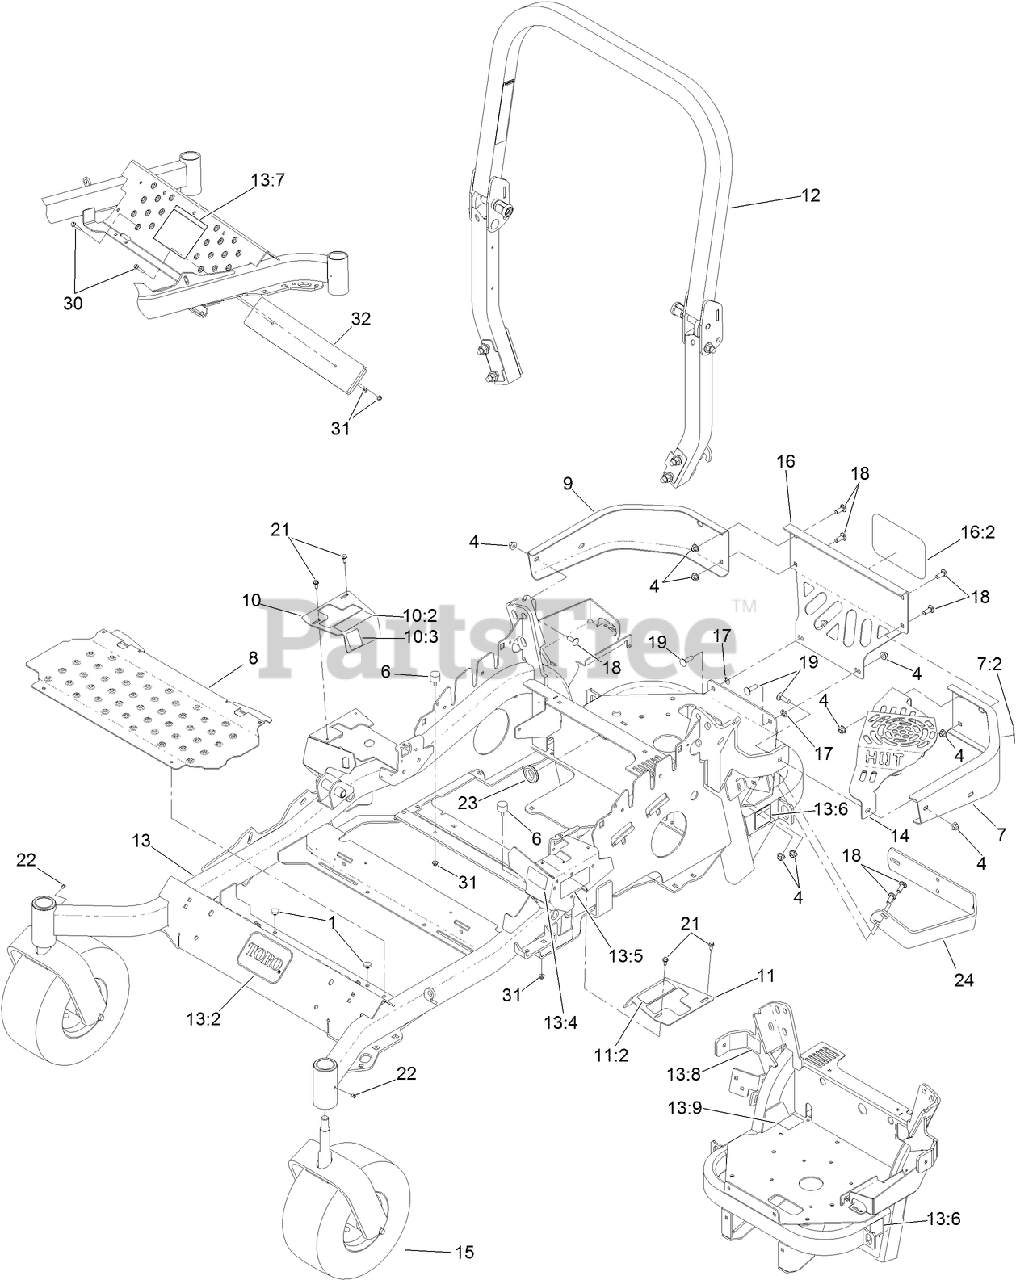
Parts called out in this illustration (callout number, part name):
1	BUMPER
4	NUT-HF, NI
6	BUMPER-RUBBER (W/ STUD)
7	BUMPER-REAR, LH
7:2	DECAL-CAUTION
8	FLOORPAN
9	BUMPER-REAR, RH
10	COVER ASM-MOTION CONTROL
10:2	DECAL-MOTION CONTROL
10:3	DECAL-PARK BRAKE
11	COVER ASM-MOTION CONTROL
11:2	DECAL-MOTION CONTROL
12	ROPS ASM
13	FRAME ASM
13:2	DECAL
13:4	DECAL-FUEL FILL
13:6	DECAL-BELT DRIVE
13:7	DECAL-SLOPE
13:8	DECAL-SPARK ARRESTER
13:9	DECAL-BYPASS
14	GUARD-MUFFLER
15	Caster Wheel ASM
16	REAR GUARD ASM
16:2	DECAL
17	NUT-PUSH
18	SCREW-CARR
19	BOLT-CARR
21	SCREW-HWH
23	GROMMET
24	GUARD-MUFFLER, SIDE
30	SCREW-HHF
31	NUT-HF
